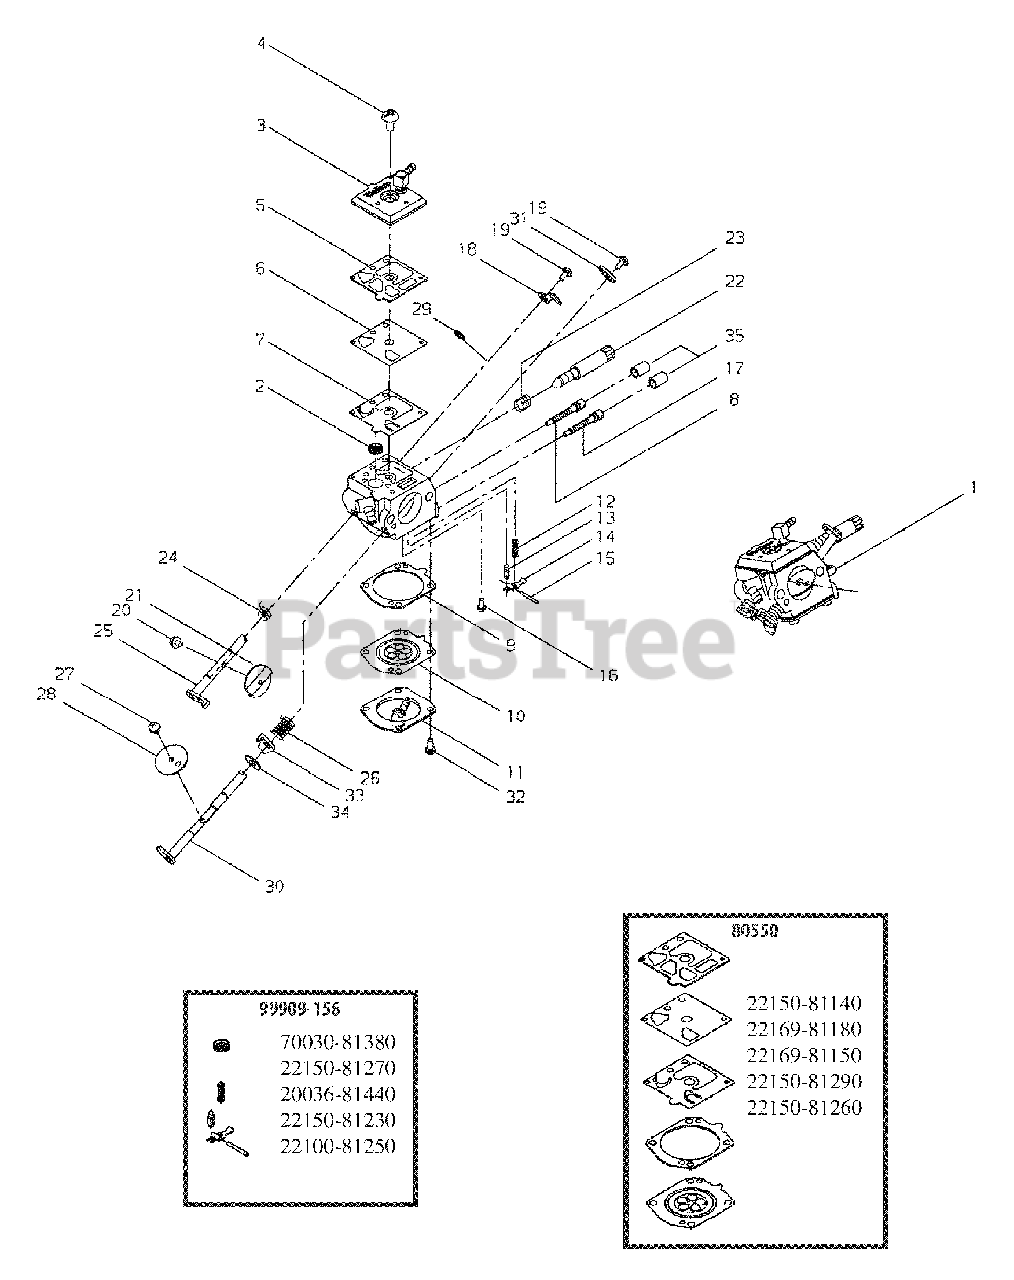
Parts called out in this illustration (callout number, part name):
1	CARBURETOR
2	STRAINER
3	COVER, PUMP
4	SCREW
5	GASKET, PUMP
6	DIAPHRAGM, PUMP
7	DIAPHRAGM, PUMP
8	NEEDLE - LOW SPEED
9	GASKET, METERING
10	DIAPHRAGM, METERING
11	COVER, DIAPHRAGM
12	SPRING, METERING LEVER
13	VALVE, INLET NEEDLE
14	LEVER, METERING
15	PIN, METERING LEVER
16	SCREW, METERING LEVER PIN
17	NEEDLE - HIGH SPEED
18	STOP, THROTTLE
19	SCREW
20	SCREW
21	VALVE, THROTTLE
22	SCREW, IDLE ADJUST
23	SPRING
24	SPRING, THROTTLE RETURN
25	SHAFT, THROTTLE
26	SPRING, CHOKE RETURN
27	SCREW
28	VALVE, CHOKE
29	RING, RETAINING
30	SHAFT, CHOKE
31	TRIGGER, THROTTLE
32	SCREW
33	LEVER, FAST IDLE
34	WASHER
35	CAP, LIMITER
80550	DIAPHRAGM/GASKET KIT
99909-156	REPAIR KIT
